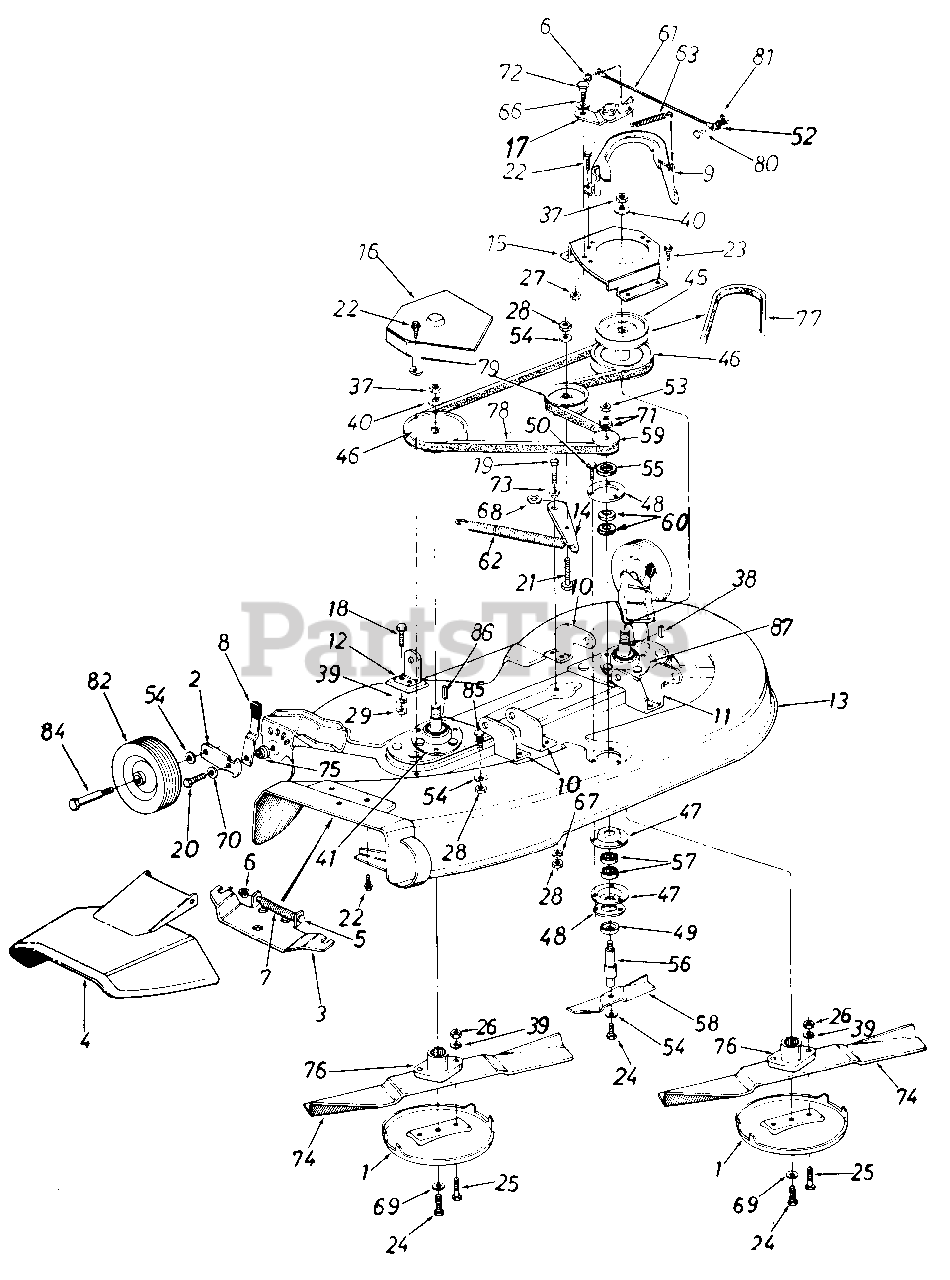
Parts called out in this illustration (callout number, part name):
1	Anti-Scalp Plate
2	Bar-Wheel Pivot
3	Adapter Plate
4	Chute Cover Ass'y.
6	Cap Speed Nut 1/4" Rod
7	Torsion Spring
8	Spring Lever Ass'y.
9	Belt Guard
12	Deck Hanger Bracket
13	44" Deck Ass'y.
14	Idler Bracket
15	Pulley Cover-L.H.
18	Hex Bolt 5/16-18 x .75" Lg.'
19	Hex Bolt 3/8-24 x 1.00" Lg.
20	Hex Bolt 3/8-24 x 1.25" Lg.
21	Hex Bolt 3/8-24 x 1.50" Lg.
22	Hex Wash. S-Tapp Scr. 1/4-20 x .50"
23	Hex Wash. Hd. Tapp Scr. 5/16-18 x .75" Lg.
24	Hex Cent. L-Bolt 3/8-24 x .88" Lg.
25	Hex Bolt Special 5/16-24 x 1-1/4" Lg.
26	Hex Nut 5/16-24 Thd.
27	Hex Cent. L-Nut 5/16-18 Thd.
28	Hex Nut 3/8-24 Thd.
29	Hex Nut 5/16-18 Thd.'
37	Hex Jam Nut 5/8-18 Thd.
38	Sq. Key 3/16" x 2.25" Lg.
39	L-Wash. 5/16" I.D.
40	Bell-Wash. .630" I.D. x 1.25" O.D.
41	R.H. Blade Spindle Ass'y.
45	5/8 "V"-Pulley .79" I.D. x 5.75" O.D.
46	"V"-Pulley .79" I.D. x 6.50" O.D.
47	Bearing Housing 1-3/8" I.D.
48	Reinforcement Plate
49	Bearing Shield
50	Hex Wash. Hd. B-Tap Scr. 1/4 x 1.0" Lg.
52	Fl-Wash. .20" I.D. x .62" O.D.
53	Hex Jam Nut 1/2-20 Thd.
54	Bell-Wash. .400" I.D. x .88" O.D.
55	Fl-Wash. .635" I.D. x 1.04" O.D.
56	6.5" Blade Spindle
57	Ball Brg. .62" I.D. x 1.38" O.D. x .44"
59	1/2" "V"-Pulley Half .625" I.D. x 2.25" O.D.
60	Fl-Wash. 5/8" I.D. x 15116" O.D.
61	Brake Cable 11.75" Lg.
62	Extension Spring .73" O.D. x 4.31" Lg.
63	Ext. Spring .50" x 2.51" Lg.
66	Spring Wash. .445" I.D. x .75" O.D.
67	L-Wash. 3/8" I.D.
68	Spring Wash. .625" I.D. x .885" O.D.
69	L-Wash. 3/8" I.D. (Heavy Duty)
70	Bell-Wash. .400" I.D. x 1.13" O.D.
71	Bell-Wash. .505" I.D. x 1.00" O.D.
72	Shld. Bolt .437" Dia. x .180"
73	Shld. Spacer .625" I.D.
75	Shld. Spacer
76	Blade Adapter
77	"V"-Belt
78	"V"-Belt
79	Fl-ldler w/Flanges 3.50" O.D.
80	Clevis Pin 1/4" Dia. x .53" Lg.
81	Intern. Cotter Pin 5/16" Dia.
82	Deck Wheel 6.0" x 1.38"
84	Shld. Bolt 3/8-16 x 1.41"
85	Rib Neck Bolt
86	Sq. Key 3/16" x 3/16" x .75" Lg.
87	L.H Blade Spindle Ass'y.
